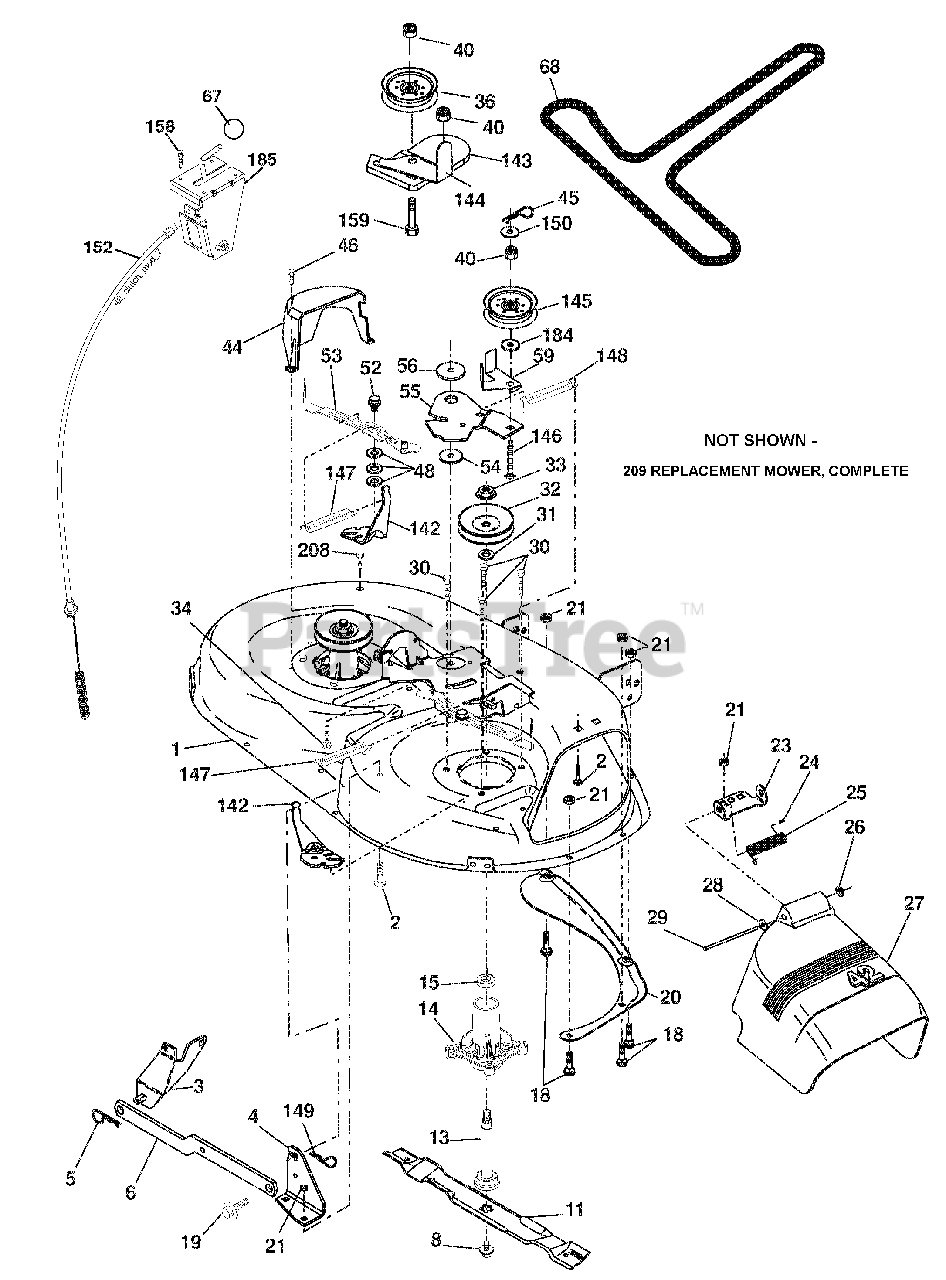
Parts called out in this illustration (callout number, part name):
1	Mower Deck Assembly, 42"
3	Bracket Asm Fr. Sway Bar 3/42
4	Bracket Asm Deck 42" Sway Bar
5	Retainer Spring
6	Bar Sway Deck
8	BOLT/WASHER ASM.7/16-20.UNF
11	BLADE.MOWER.42"HI LIFT PREMIUM
11	BLADE, HUSQ MULCH KIT
11	Blade Mulching 42 Premium (Fo
11	Blade 42SP" 3N1
11	Blade 42SP" 3N1 Premium
13	SHAFT ASM.MNDRL.N/GREASEABLE38
14	HOUSING.MANDREL.4PT.SERVICE
15	BEARING.BALL.MANDREL
18	BOLT.RDHD.SQNK.5/16-18 X 5/8
19	Bolt, Shoulder
20	BAFFLE.VORTEX.42.STD/HEAVY DTY
21	Nut, Hex, Crownlock 5/16-18
23	Bracket, Deflector Mower 42"
24	CAP.SLEEVE..80X.112.BLK.MOWER
25	SPRING.TORSION.DFL.38/42/46.GR
26	NUT.PUSH.PHOS.& OIL
27	Shield, Deflector 42" Blk
28	Washer 11/32 x 5/8 x 16 Ga.
29	ROD.HINGE.42/46"
30	SCREW.THD ROLL.DOD PT.HEX
31	WASHER.SPACER.MANDREL
32	MANDREL.PULLEYS.42,44,50
32	MANDREL ASM.SUB.N-GRS.4 BOLT
32	AND BEARING ONLY - PULLEY/NUT/WASHER AND BLADE BOLT/WASHERS NOT INCLUDED)
33	NUT.FLANGE.LOCK.TOP
34	BOLT.CARR.SH.3/8-16X1-1/2.GR5
36	PULLEY, IDLER, FLAT
40	Nut, Hex, Flangelock 3/8-16
44	Guard, Mandrel, LH
45	Retainer Spring
46	SCREW.THD.ROLL.1/4-20 X 5/8
48	Washer, Hardened
52	Bolt, Shoulder 5/16-18 unc
53	Arm Assembly, Pad, Brake
54	WASHER.FLAT.HARDENED
55	Arm, Idler
56	Spacer, Retainer
59	GUARD.TUV.IDLER
67	Knob Round
68	V-Belt, 42" Mower
142	Anchor Spring Brake Mower
143	Bracket Arm Idler 42"
144	KEEPER BELT 42" CLUTCH CABLE
145	PULLEY IDLER FLAT
146	BOLT.CARRIAGE.IDLER
147	Spring Extension
148	Spring Return Idler
149	Retainer Spring Yellow
150	WASHER.9/32 X 3/4 X 10 GA.
152	Clutch Cable 42"
158	Screw 1/4-20 x 1/2
159	Bolt Rdhd Sqn 3/8-16 unc x 1-3
184	Washer 13/32 x 7/8 x 10 Ga.
185	Head Asm Cable Clutch\
208	SCREW.THDROL.3/8-16X1/2.TYT.BL
209	Replacement Mower, Complete
